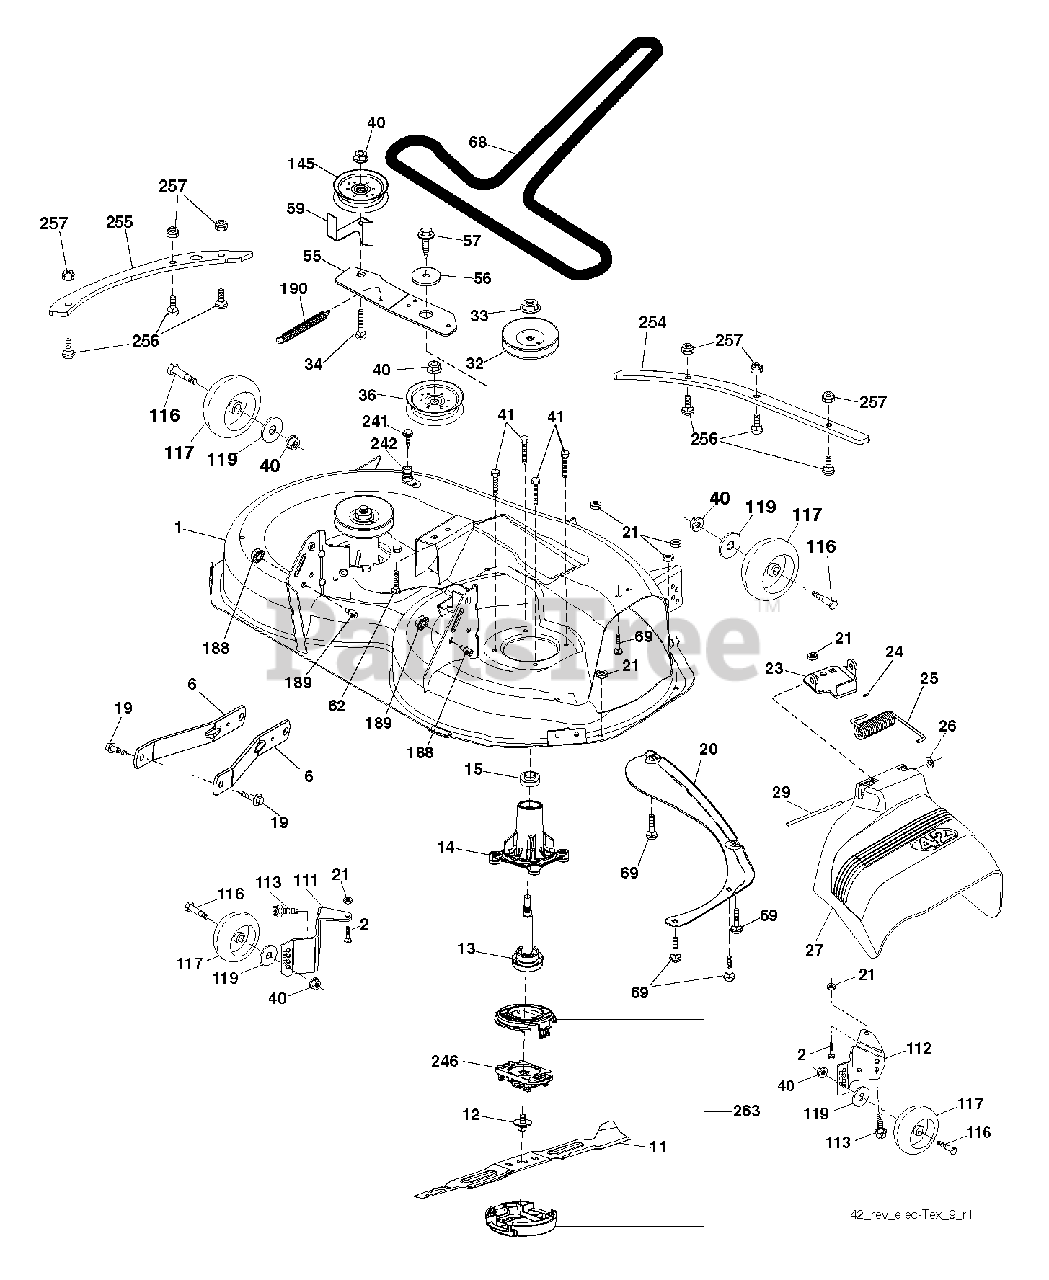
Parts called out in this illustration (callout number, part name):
1	Mower Deck Assembly, 42"
2	BOLT
6	ARM.SUSPENSION.MOWER.R
11	Mower Blade, Revolution 42" 3-in-1 Pt43
12	Screw, 7/16 X 20 X 1"
13	SHAFT ASM.REV.TALL.N/GREASEBL
14	HOUSING.MANDREL.REV.TALL.N/GRS
15	Extended Mandrel Bearing, Top
19	BOLT.SHOULDER
20	BAFFLE.VORTEX
21	LOCKNUT
23	BRKT.DEFLECTOR.38"2005+
24	CAP-SLEEVE LT
25	SPRING.TORSION.DEFLECT
26	NUT PUSH M
27	SHIELD.DEFLECTOR.MOWER.42"BLAC
29	ROD.HINGE
32	PULLEY/MANDREL
33	NUT.FLANGE.LOCK.TOP
34	BOLT.3/8-16X1.50
36	PULLEY.IDLER.2006
40	NUT LOCK FLG 3/8-16 UNC
41	Hex Washer Head Bolt, .313-18 X 1.19
55	IDLER.ARM.42"
56	SPACER.RETAINER
57	SCREW 3/8-16X1
59	GUARD, BELT
62	BOLT
68	BELT V SECONDARY
69	BOLT
111	BRKT.WHEEL.GAUGE.LH.42"
112	BRKT.WHEEL.GAUGE.RH.42"
113	BOLT.5/16HEX.WHS.HD
116	BOLT M
117	WHEEL.GAGE.HALF.SPOKED
119	WASHER
145	PULLEY.IDLER.48"PRIMARY
188	STUD.FASTNER.W/ANTI-ROTATE
189	NUT LOCK HEX FLANGE 5/16-18
190	SPRING.MOWER.DRIVE.ELECTRIC
241	SCREW.TT.#10-32X.5.3/8.FLANGE
242	PORT.WASHOUT
246	Blade Holder, Revolution
254	Front Reinforcement Plate, 42" Deck.Ftx498
255	Side Reinforcement Plate, 42"
256	RHSNB, 1/4-20 X 1, GR5
257	NUT T
263	Revolution Assembly Cap, Upper
